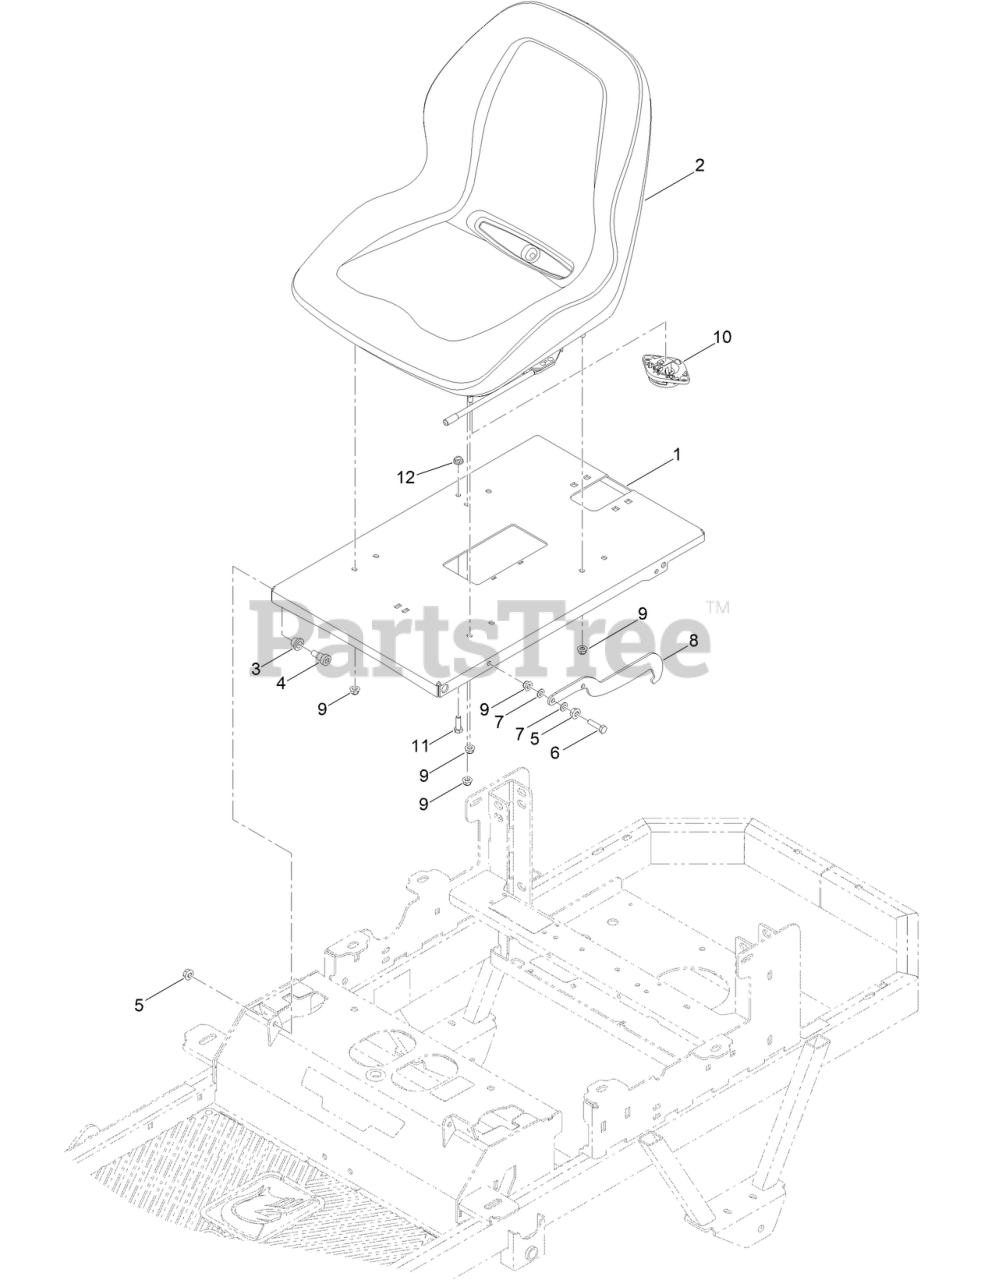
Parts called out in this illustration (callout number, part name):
1	PLATE-SEAT BASE UPGRADE W/ DECALS ASM
1	RZ MWR SEAT BRTK PAINT
2	2021 RZ SEAT
3	1/2IN ID X 5/8IN OD X 1/2IN FLANGE BUSH
4	1/2 X 1/2 SOCKET SHOULDER BOLT ZC YELLOW
6	SCREW-HH
7	.312IDX.625ODX.062 THK THRUST BRG OI BRZ
8	MWR SEAT LATCH HOOK PAINT
9	NUT-HF, NI
10	MWR SEAT SWITCH
11	SCREW-HH
12	NUT-HF
